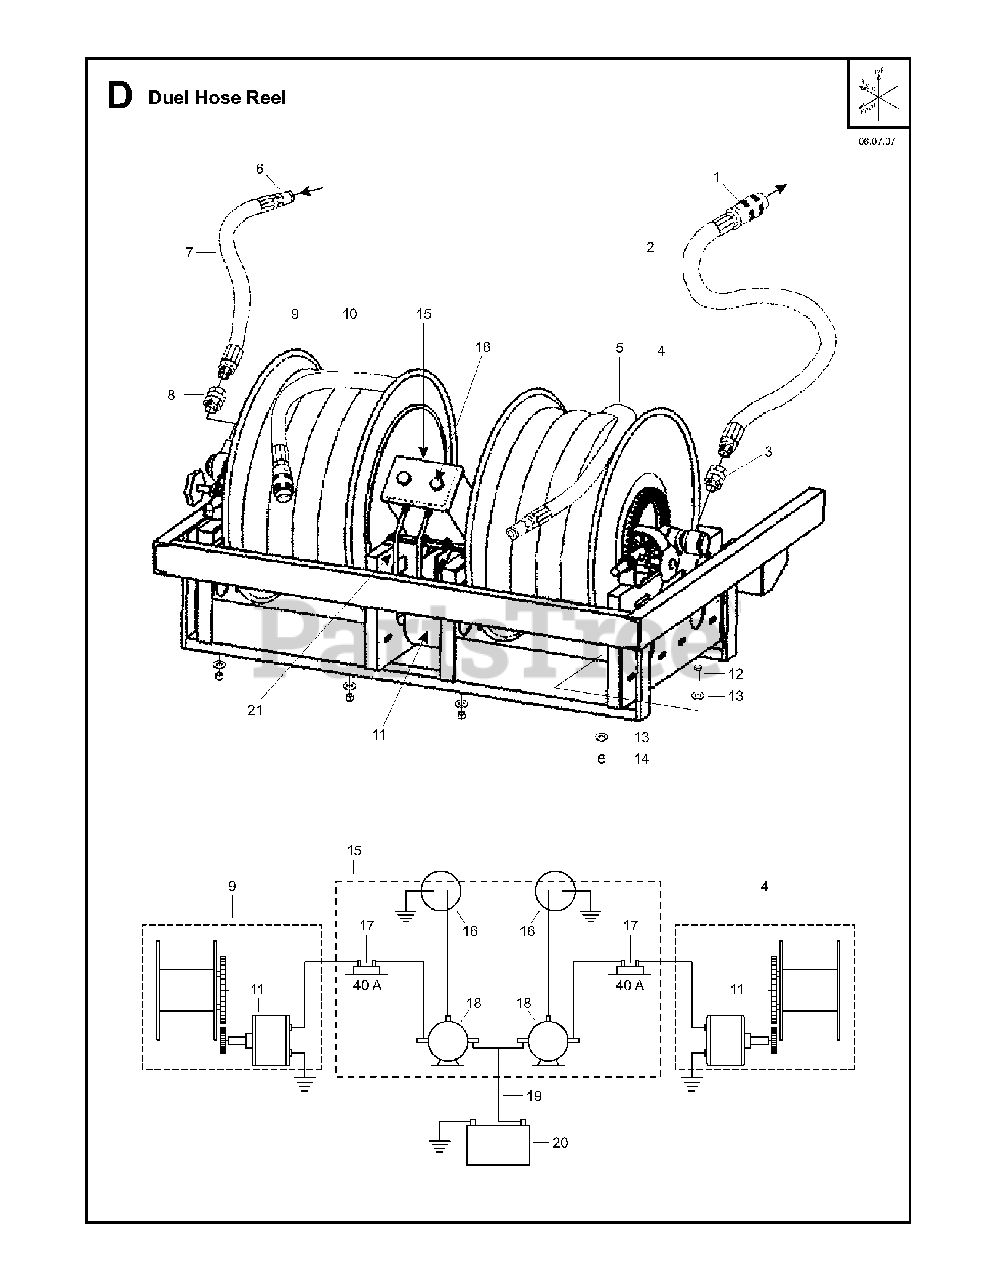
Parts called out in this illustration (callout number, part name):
4	HYDRAULIC HOSEIncls: 11
9	HYDRAULIC HOSEIncls: 11
12	HHCS. M10 x 1.5 x 25 DIN933 ZP
14	LOCKNUT. FIBER M10 DIN 985
